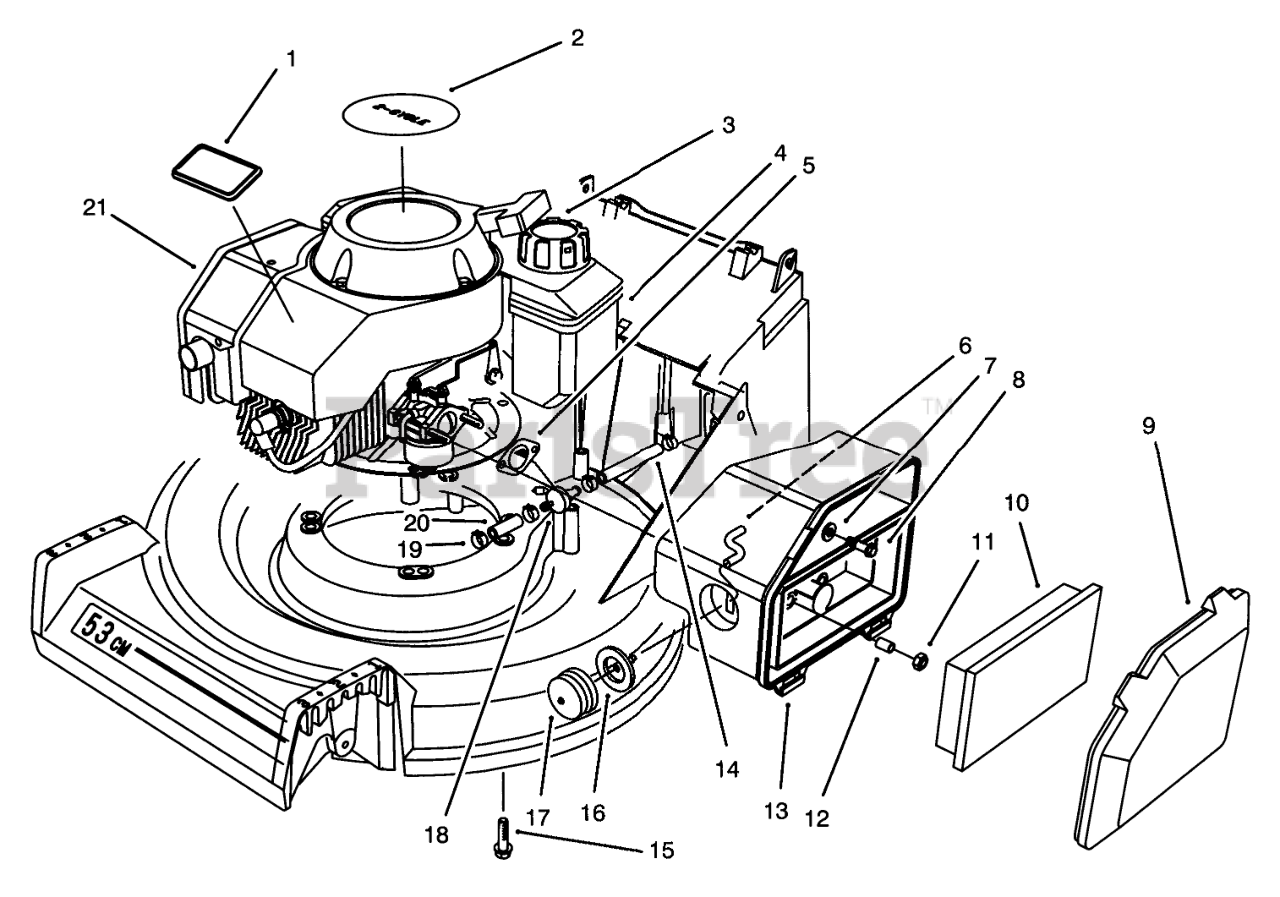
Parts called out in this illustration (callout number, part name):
1	TORO LOGO PLT
2	DECAL- 2 CYC RECOIL
3	GAS CAP ASM
4	FUEL TANK ASM
5	GASKET-AIR CLEANER
6	HOSE-PRIMER
7	WASHER-FLAT
8	SCREW-HH
9	COVER-AIR CLEANER
10	ELEMENT-AIR CLEANER
12	SPACER
13	BODY-AIR CLEANER
14	HOSE-FUEL
15	Bolt-Engine
16	BODY-PRIMER
17	BULB-PRIMER
18	FILTER-FUEL
19	CLAMP-FUEL LINE
20	HOSE-FUEL
21	ENGINE 121CC INT'L 2CYC
